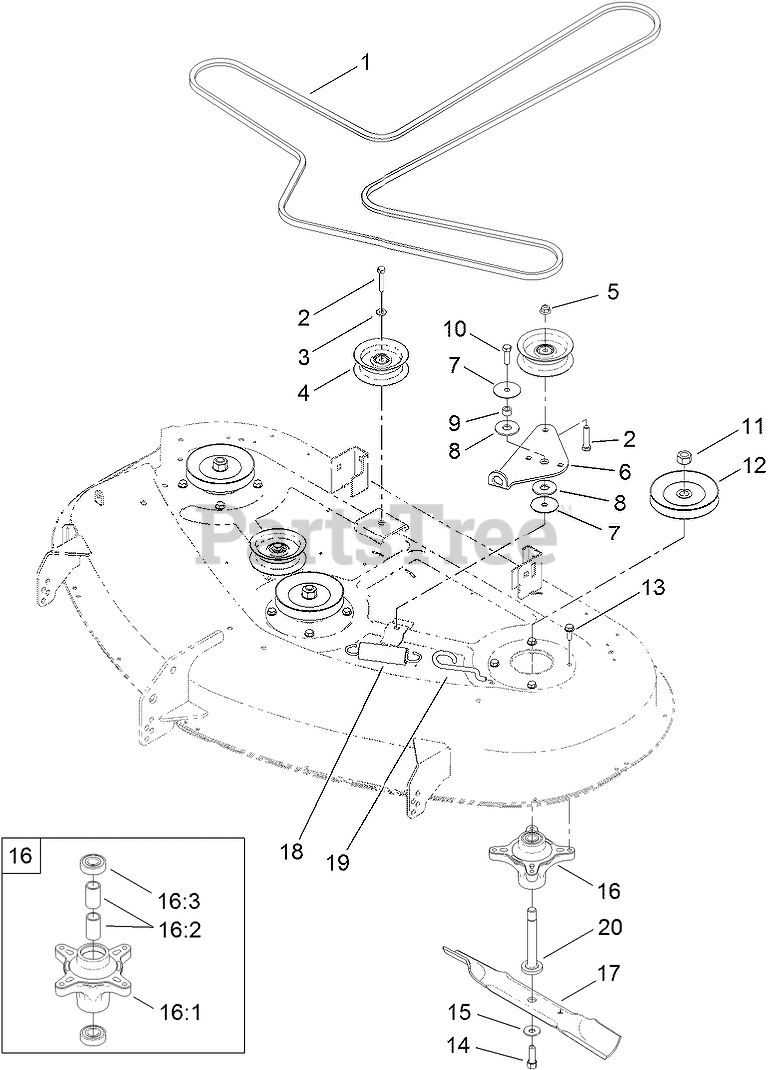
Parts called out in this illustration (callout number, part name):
1	V-BELT
2	SCREW-HH
3	WASHER-FLAT
4	PULLEY-IDLER, FLAT
5	NUT-HF, NI
6	ARM-IDLER
7	WASHER
8	WASHER-FRICTION, COMPOSITE
9	SPACER
10	SCREW-HH
11	NUT-HEX
12	PULLEY
13	SCREW-TAPTITE
14	SCREW-HH
15	WASHER-BELLEVILLE
16	SPINDLE ASM
16:1	SPINDLE
16:2	SPACER
16:3	BEARING-BALL
17	BLADE-MULCH, 17.50 INCH
18	SPRING-EXTENSION
19	HOOK-RETURN, SPRING
20	SHAFT-SPINDLE
